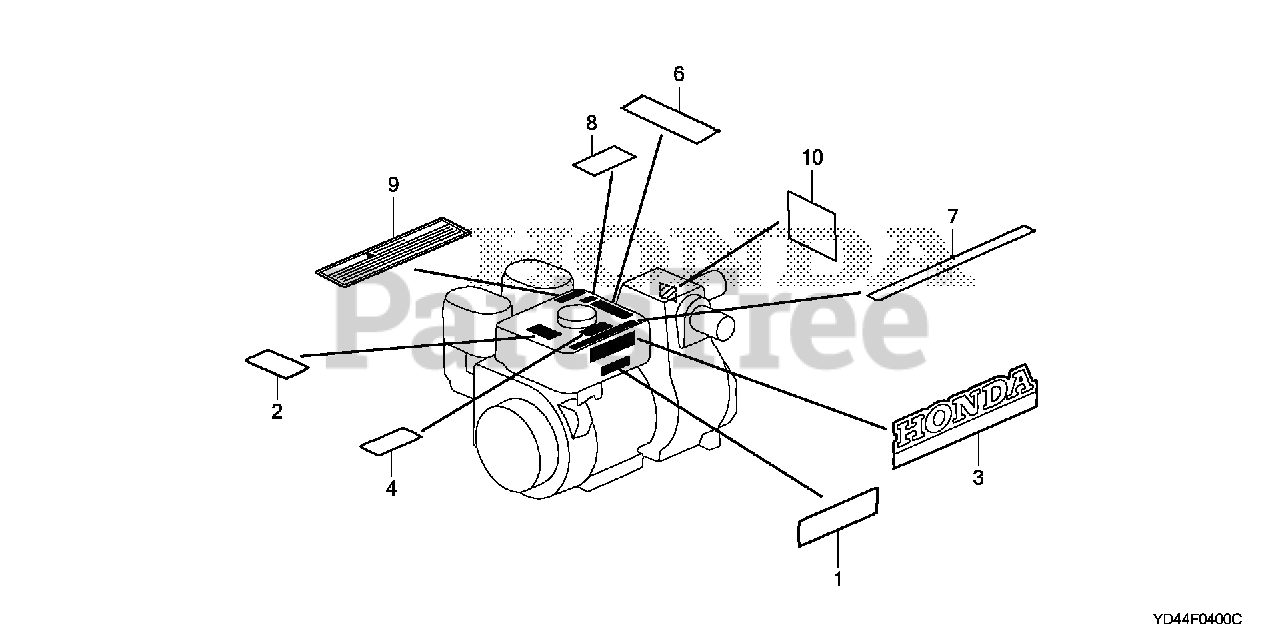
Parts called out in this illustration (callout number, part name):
2	LABEL, PUMP WARNING (ENGINE NO.)
6	MARK, CAUTION (PUMP)
7	MARK (WT40X)
8	LABEL, PUMP WARNING (ENGINE NO.)
9	LABEL, SPARK WARNING
